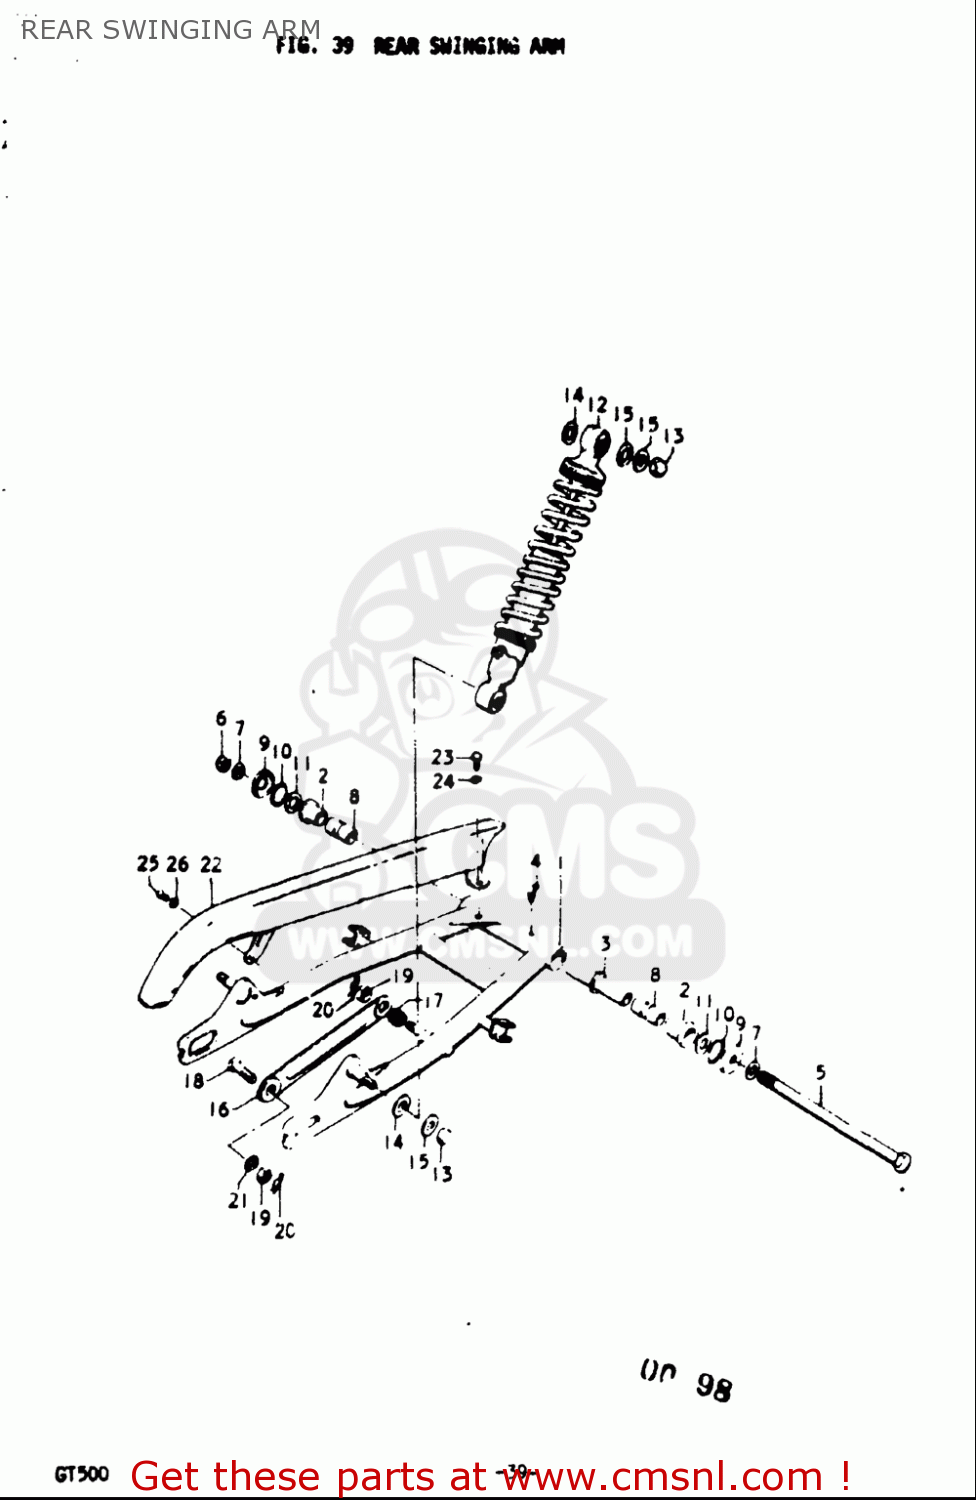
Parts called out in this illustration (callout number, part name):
2	BUSH
4	NIPPLE,GREASE
5	SHAFT,REAR SWING ARM
7	WASHER
8	SPACER
9	COVER
10	O RING(D:3,ID:29.5)
11	WASHER(14.5X29X2.3)
13	NUT
14	WASHER
15	WASHER (10.5X24X2.3)
17	SPRING
18	BOLT(10X31)
19	NUT
20	CLIP
21	WASHER,LOCK
